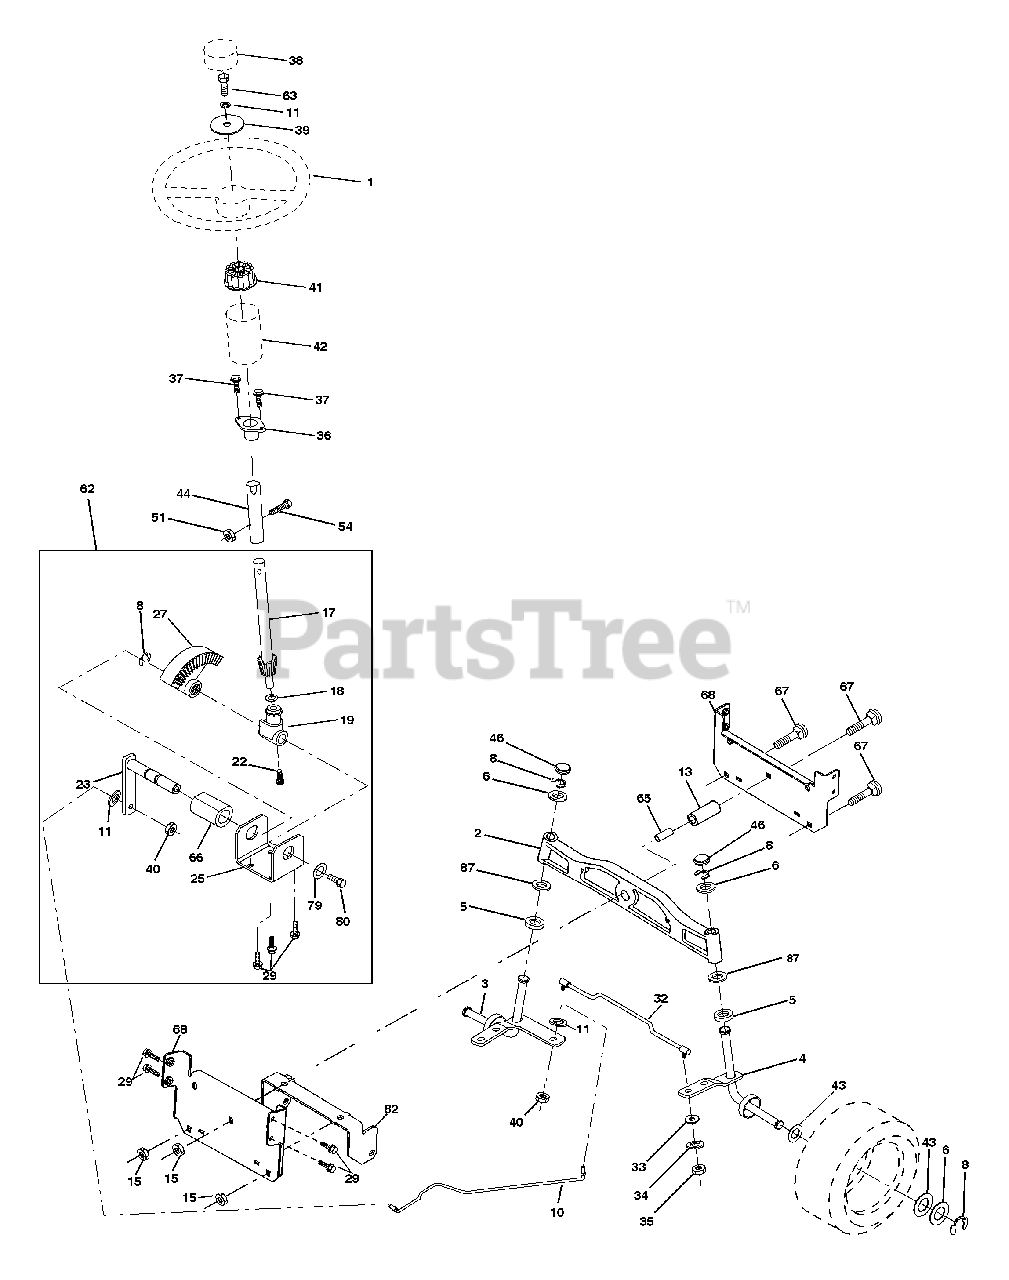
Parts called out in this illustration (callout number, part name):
1	Wheel Steering
2	Axle Asm Cast Iron LT
3	Spindle Asm LH
4	Spindle Asm RH
5	Bearing Race Thrust Harden
6	Washer 25/32 X 1-5/8 X 16 Ga
8	Ring Klip #t5304-75
10	Link Drag
11	Washer Lock Hvy Hlcl Spr 3/8
13	Spacer Brg Axle Front
15	Nut Hex Flange Lock
17	Shaft Asm Strg
18	Washer Thrust
19	Support Shaft Steering
22	Screw Hex Wshhd Torx
23	SHaft Asm Pittman
25	Bracket Steering
27	Gear Sector
29	Screw 3/8-16 x .75
32	Rod Tie
33	Washer 11/32 x 3/4 x 16 Ga
34	Washer Lock Hvy Hlcl Spr 5/16
35	Crownlock Nut 5/16-24 Unf
36	Bushing Strg
37	Screw
38	Insert Cap Strg Wh
39	Washer 13/32 X 1-1/2 X 11 Ga
40	Lock nut
41	Adaptor Wheel Strg
42	Boot Steering Dash
43	Washer 25/32 X 1 1/4 X 16 Ga
44	Extension Steering Shaft LR/LT
46	Cap Spindle Fr Top Blk
51	Nut Lock Hex w/Ins 5/16-18
54	Bolt Fin Hex 5/16-18 Unc x 1-1/4
62	Kit Steering Asm Service
63	Bolt Fin Hex 3/8-16unc x 1 Gr. 5
65	Spacer Brace Axle
66	Bearing Arm Pittman
67	Bolt Rdhd Sq 3/8-16 Unc x 2-3/4
68	Axle, Brace
79	Washer 13/32 x 1-1/4 x 12 Ga.
80	Bolt Hex Nylon 3/8-16 x 3/4
82	Bracket Susp Chassis Front
87	Washer Flat .781 x 1-1/2 x .14
